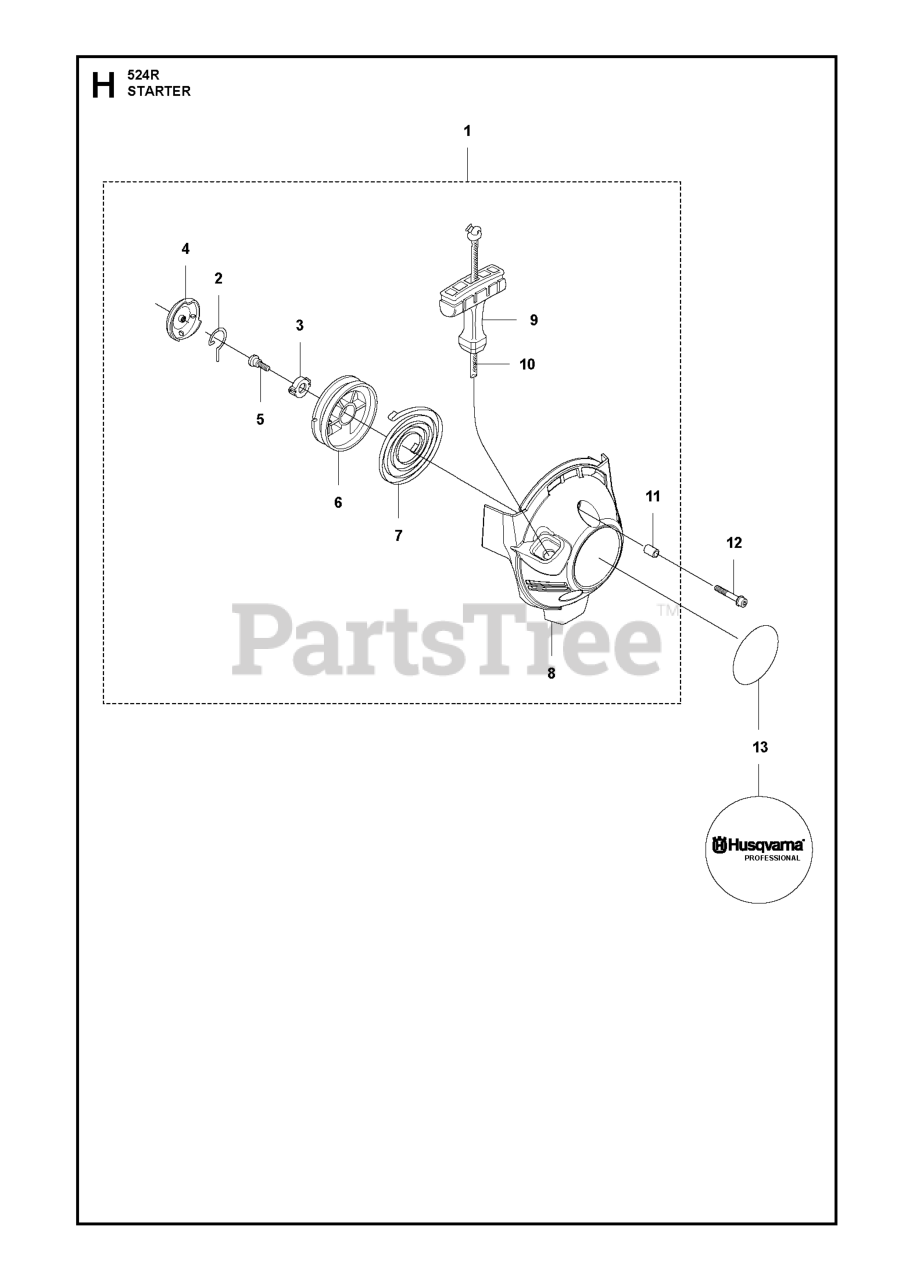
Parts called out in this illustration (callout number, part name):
1	STARTER DEVICE
6	STARTER PULLEY
7	RETURN SPRING
8	STARTER HOUSING
9	STARTER HANDLE
10	STARTER ROPE
